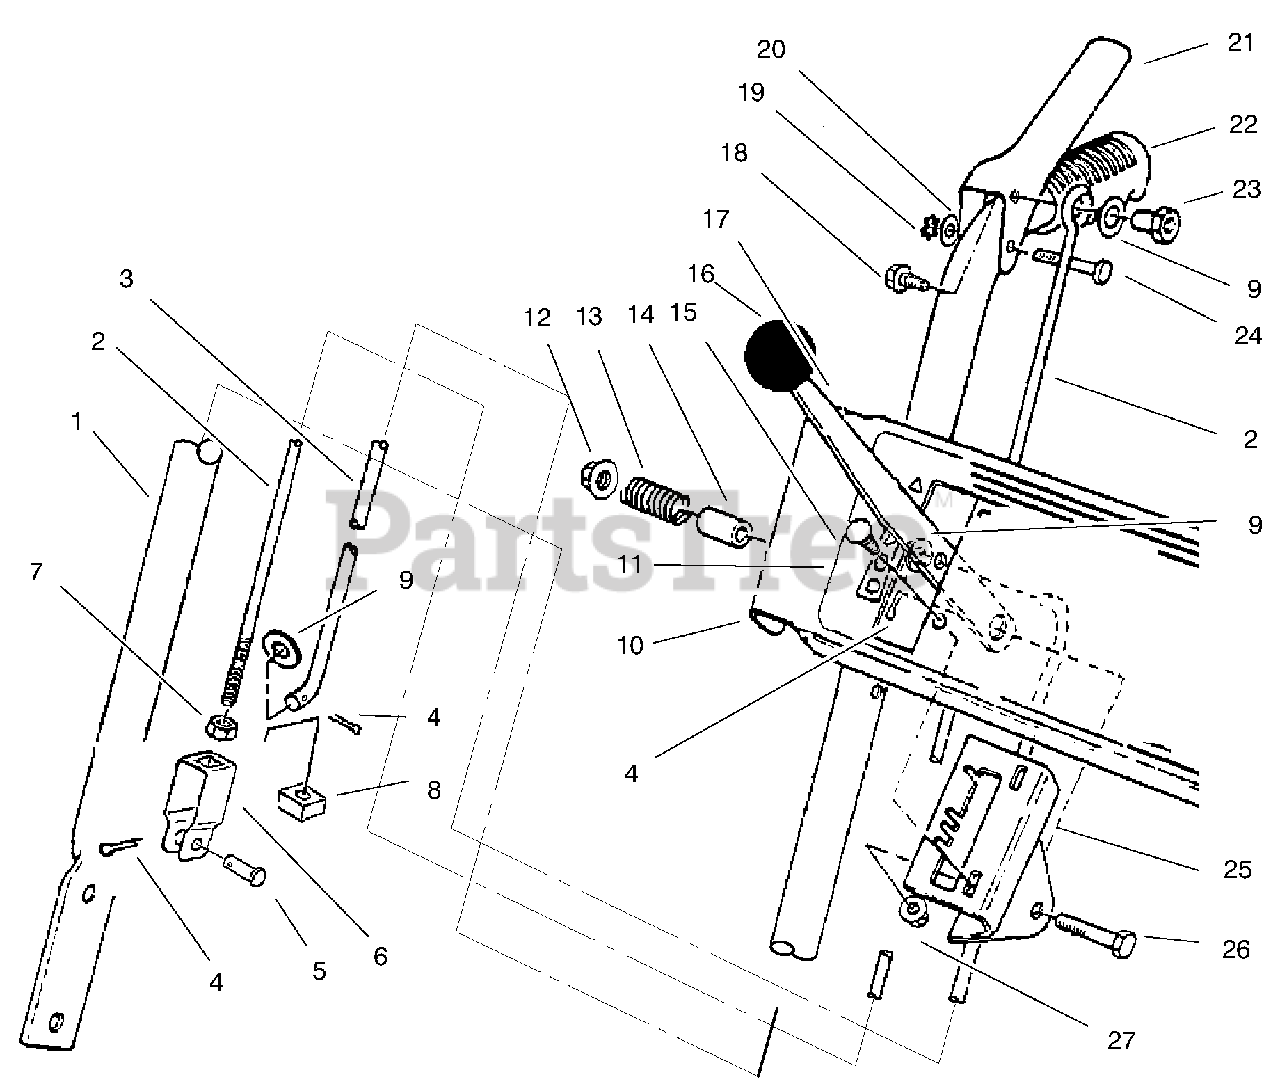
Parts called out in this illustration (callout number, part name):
1	Handle-Right
2	Link-Upper
3	Rod-Speed Selector
4	Pin-Cotter
5	Pin-Clevis
7	Nut-Jam
8	Retainer-Nut
10	Panel-Escutcheon Ass'y
11	Decal-Escutcheon
12	Nut-Flange Lock
14	Spacer-Speed Selector
15	Bolt-Carriage
17	Selector-Speed
18	Screw-Hex. Flange Hd.
19	Ring-Clip
21	Handle-Control
22	Grip-Handle
23	Post-Linkage Mounting
24	Pin-Control Lever
25	Mount-Speed Selector
27	Nut-Flange Lock
